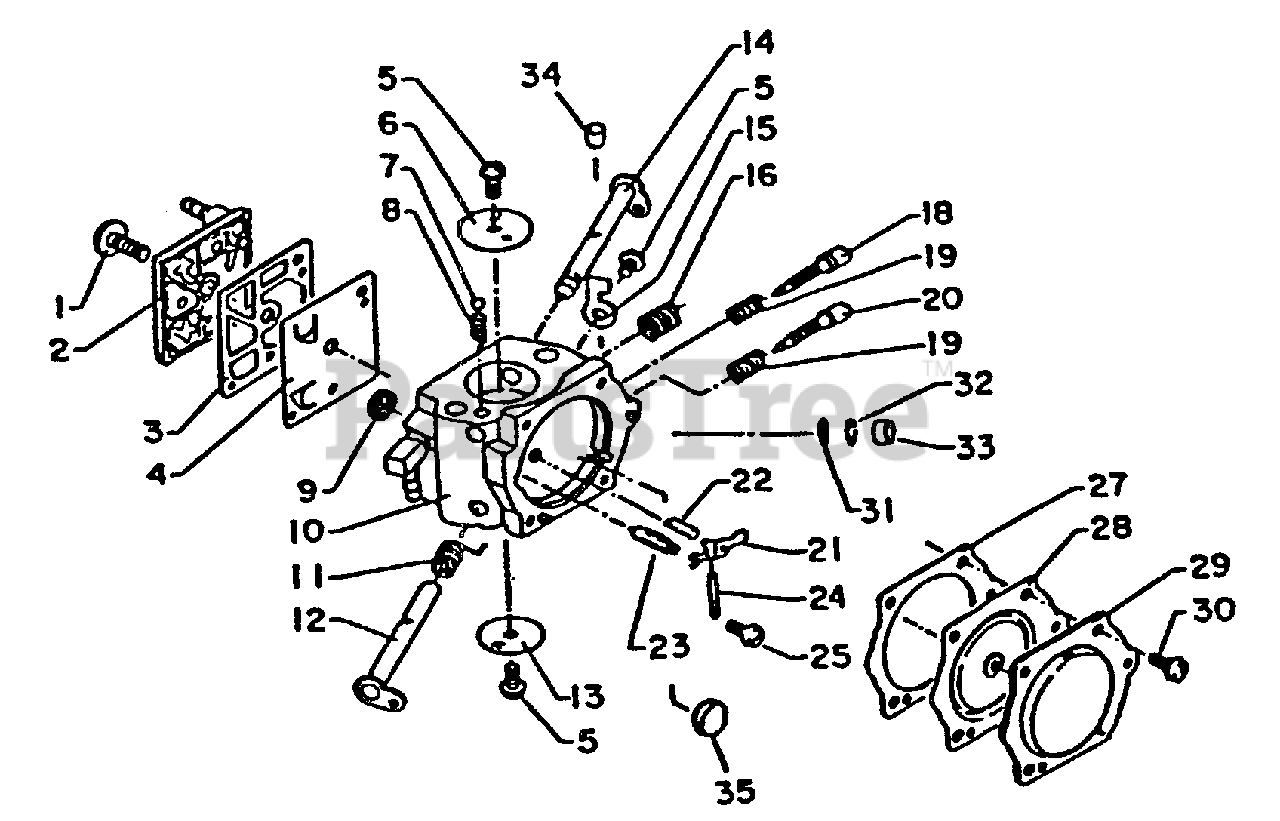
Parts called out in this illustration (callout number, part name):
2	COVER, FUEL PUMP
3	REPAIR KIT, CARBURETOR
3	GASKET / DIAPHRAGM KIT
4	REPAIR KIT, CARBURETOR
4	GASKET / DIAPHRAGM KIT
6	VALVE, CHOKE
7	BALL, CHOKE FRICTION
9	REPAIR KIT, CARBURETOR
10	BODY, CARBURETOR
11	SPRING, THROTTLE RETURN
12	SHAFT, THROTTLE
13	VALVE, THROTTLE
14	SHAFT, CHOKE
15	STOP, THROTTLE
16	SPRING, IDLE ADJUST
18	NEEDLE, IDLE
19	REPAIR KIT, CARBURETOR
20	NEEDLE, HIGH SPEED
21	REPAIR KIT, CARBURETOR
22	REPAIR KIT, CARBURETOR
23	REPAIR KIT, CARBURETOR
24	REPAIR KIT, CARBURETOR
25	REPAIR KIT, CARBURETOR
27	REPAIR KIT, CARBURETOR
27	GASKET / DIAPHRAGM KIT
28	REPAIR KIT, CARBURETOR
28	GASKET / DIAPHRAGM KIT
29	COVER, METERING DIAPHRAGM
30	REPAIR KIT, CARBURETOR
31	REPAIR KIT, CARBURETOR
32	REPAIR KIT, CARBURETOR
33	REPAIR KIT, CARBURETOR
34	PLUG, FRICTION
35	REPAIR KIT, CARBURETOR
